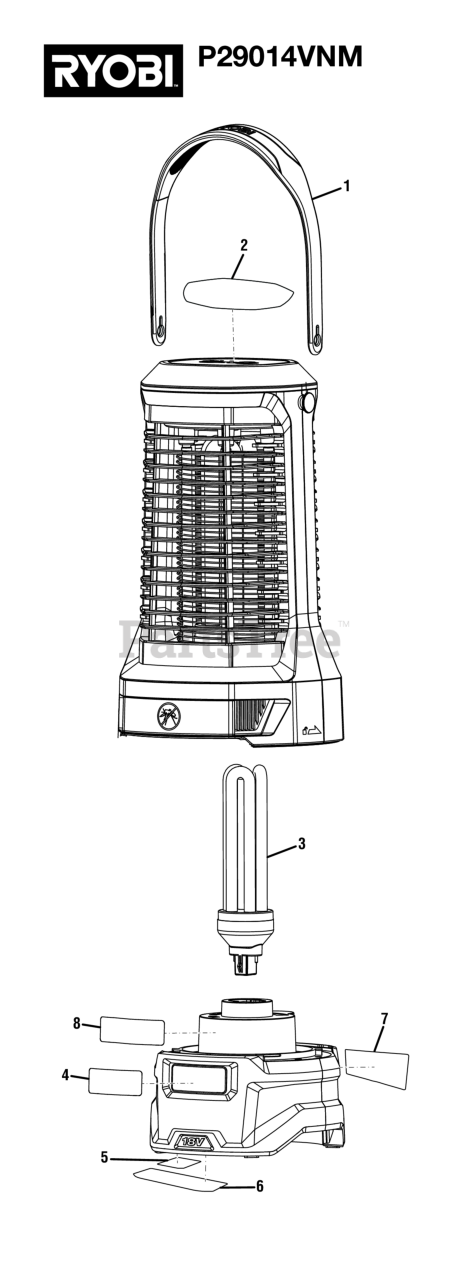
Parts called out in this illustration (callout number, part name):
2	On/Off Label
4	Logo Label
6	Data Label
7	Icon/Caution Label
8	Light Specification Label
